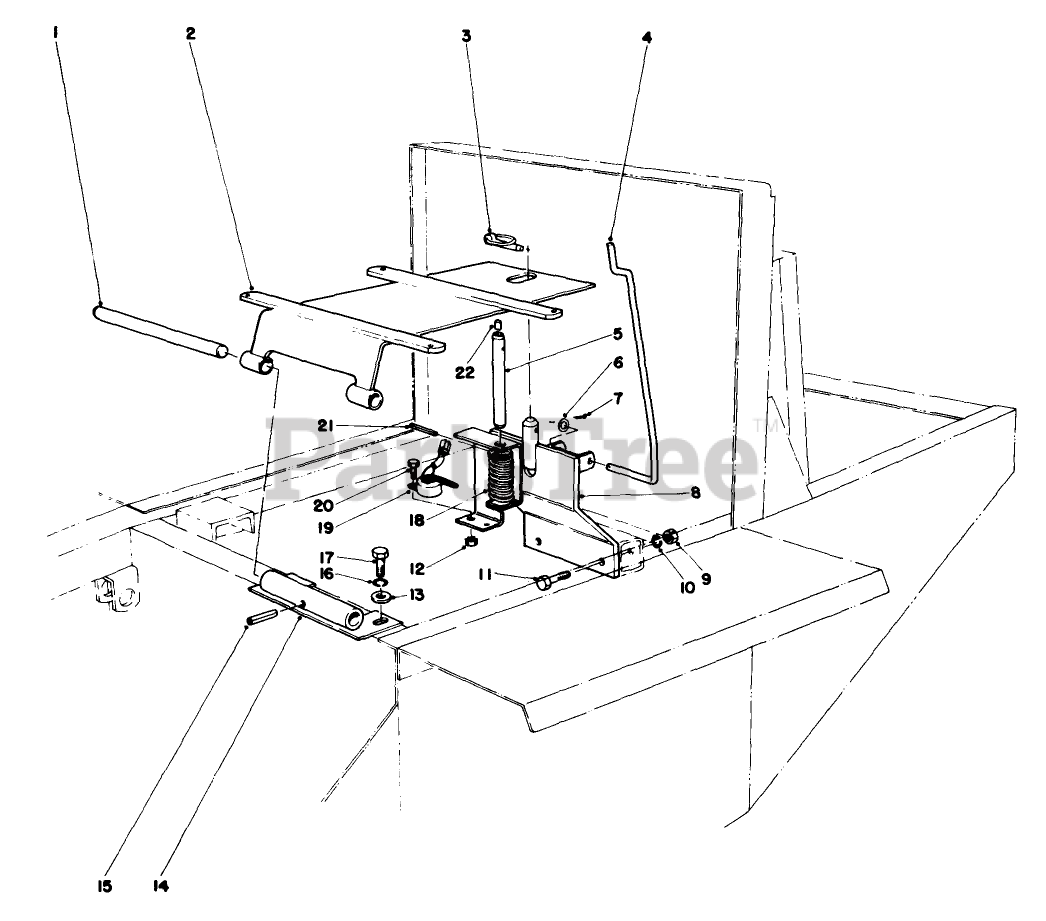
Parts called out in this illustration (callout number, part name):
1	SHAFT-PIVOT, SEAT
2	SEAT SUPPORT WA
3	PIN-LYNCH
4	Seat Prop
5	PIN-SWITCH, SEAT
6	WASHER-FLAT
7	PIN-COTTER
8	Bracket-Seat Support
9	NUT-HEX
10	WASHER-LOCK
11	SCREW-HH
12	NUT-LOCK, NI
13	WASHER-PLAIN
14	Pivot-Seat
15	PIN-ROLL, SLOTTED
16	WASHER-LOCK
17	SCREW-HH
18	SPRING-COMPRESSION
19	SWITCH ARM
20	SCREW-HH
21	PIN-ROLL, SLOTTED
22	PIN-PEDAL
